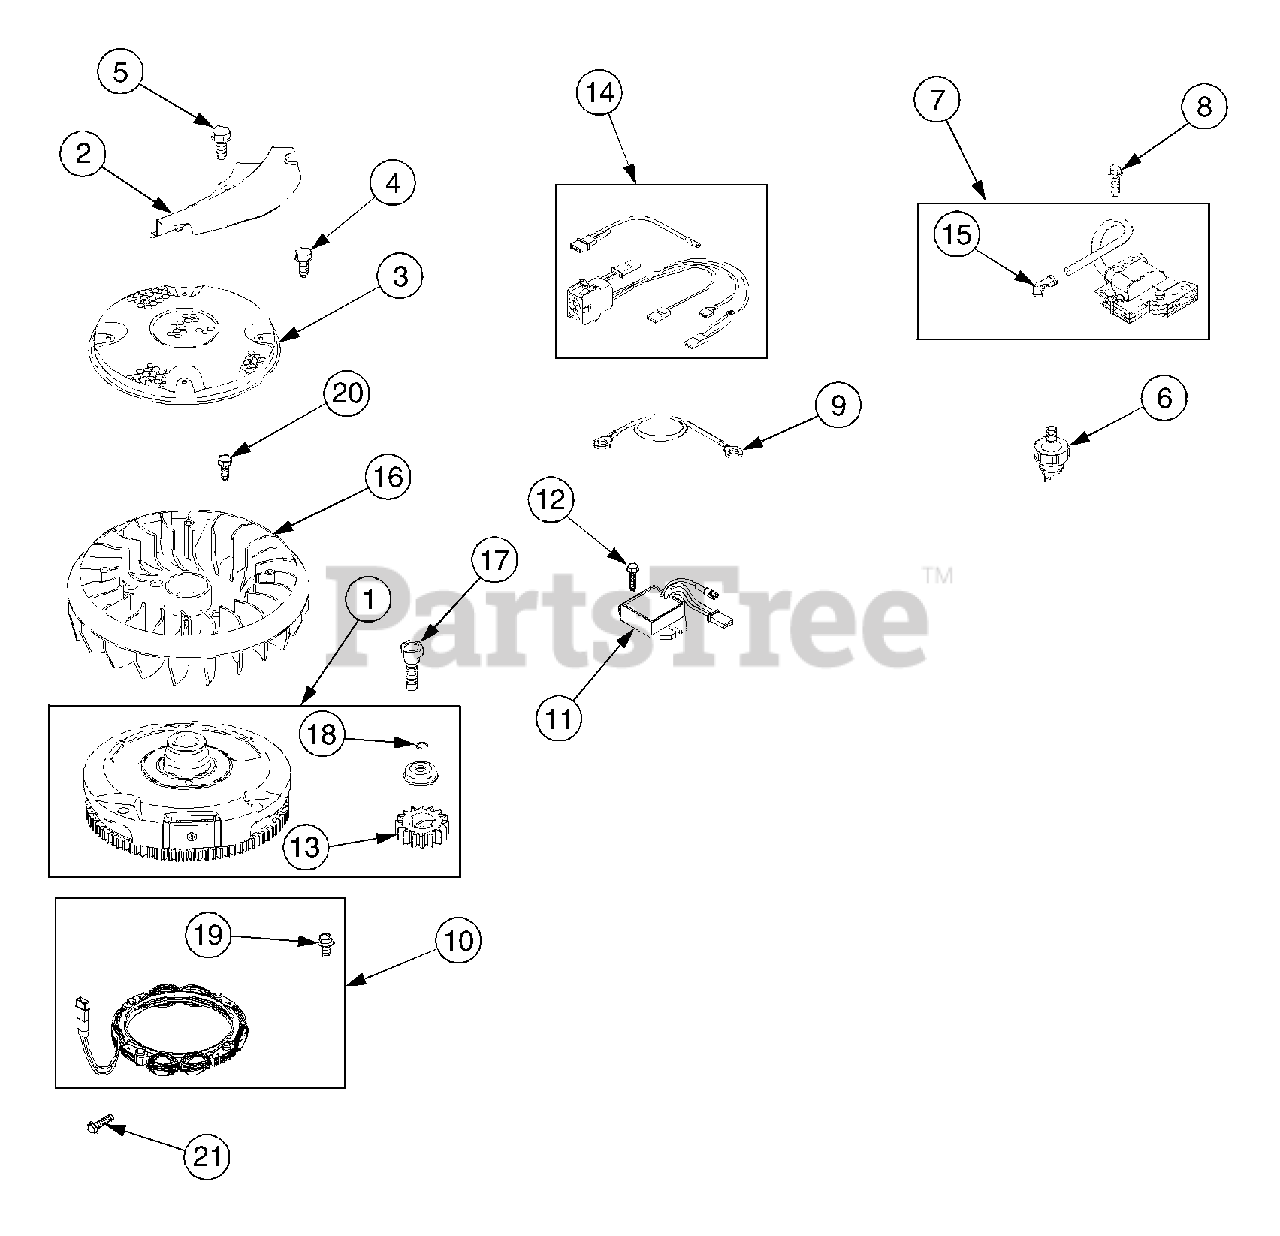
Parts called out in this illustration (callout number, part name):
2	Guard, Flywheel
3	Screen, Rotating
4	Screw (Rotating Screen)
5	Screw (Flywheel Guard)
6	Switch, Oil Pressure
7	Armature, Magneto
8	Screw (Armature)
9	Wire, Stop
10	Alternator
11	Regulator
12	Screw (Regulator)
13	Gear, Pinion
14	Harness, Wiring
15	Terminal, Spark Plug
16	Fan, Flywheel
17	Screw (Flywheel)
18	Ring, Retaining
19	Kit, Screw/Washer
20	Screw (Flywheel Fan)
21	Screw (Alternator)
